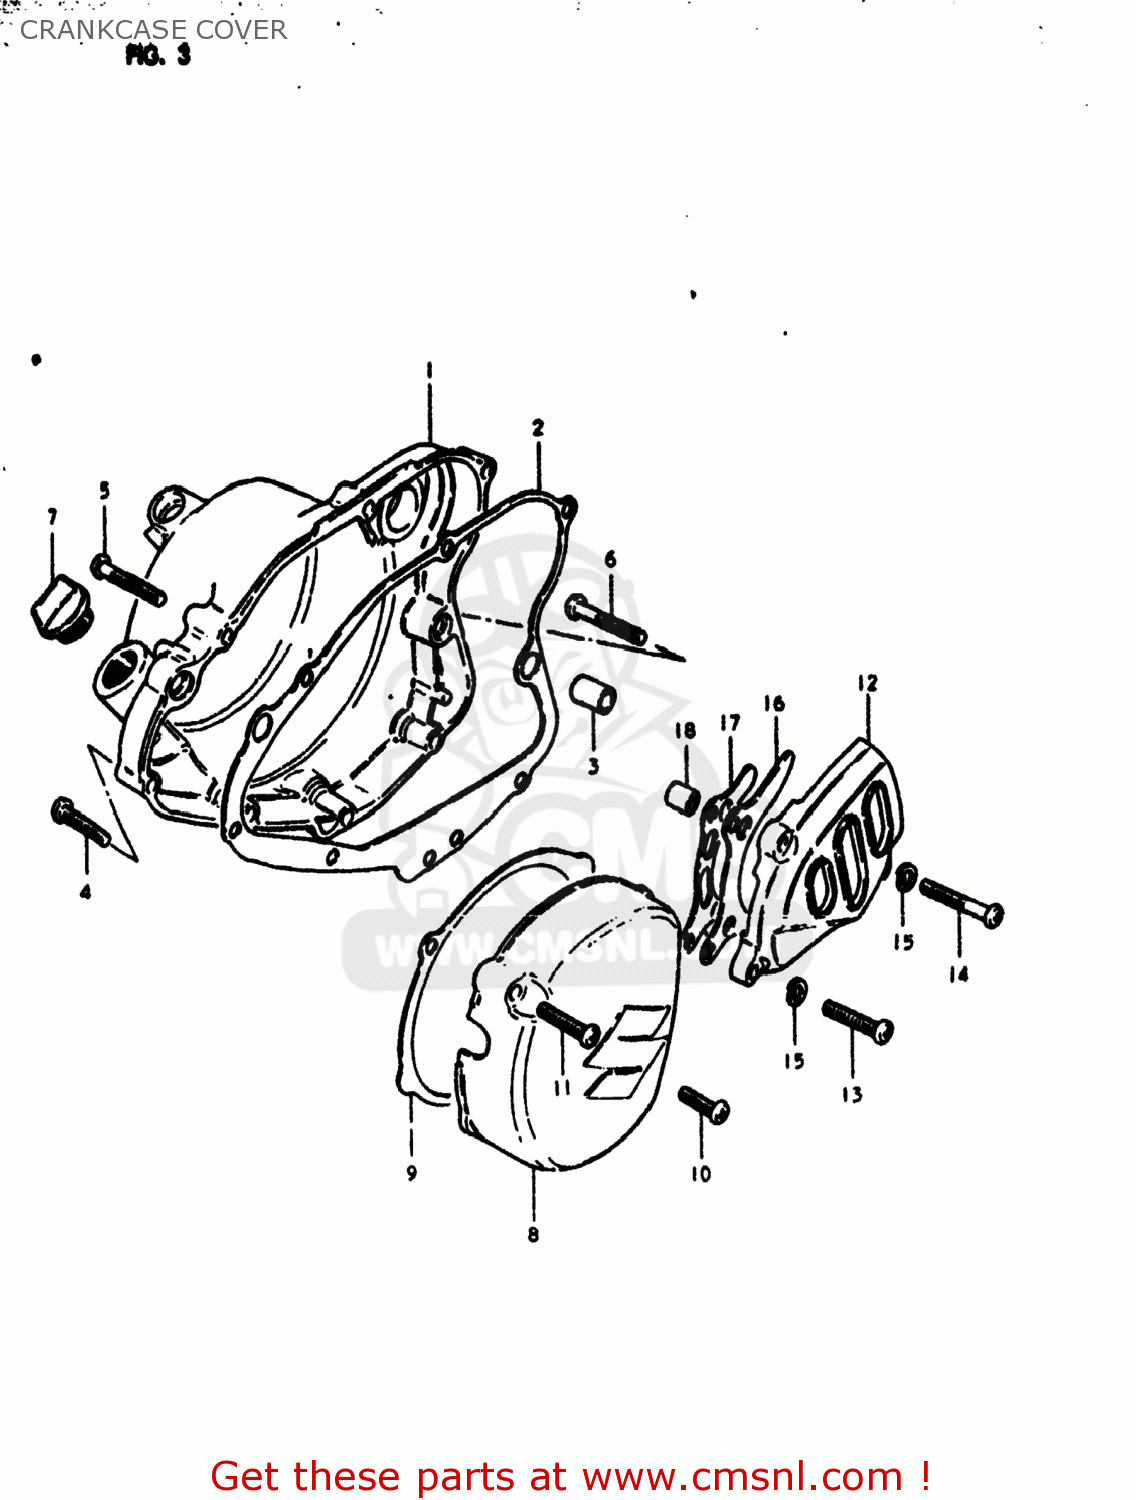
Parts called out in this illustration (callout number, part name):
1	COVER,CLUTCH
2	GASKET,CLUTCH COVER (MCA)
3	PIN
4	SCREW 6X30
5	SCREW
6	SCREW (6X45)
7	PLUG,OIL FILTER
8	COVER
9	GASKET,MAGNETO COVER (MCA)
10	SCREW
11	SCREW 6X30
12	COVER,ENGINE SPROCKET
13	BOLT 6X35
14	SCREW (6X45)
15	LOCK WASHER
16	PLATE,CHAIN FRONT GUIDE
17	PLATE,FRONT CHAIN GUIDE
18	SPACER(6.5X10.5X12)
